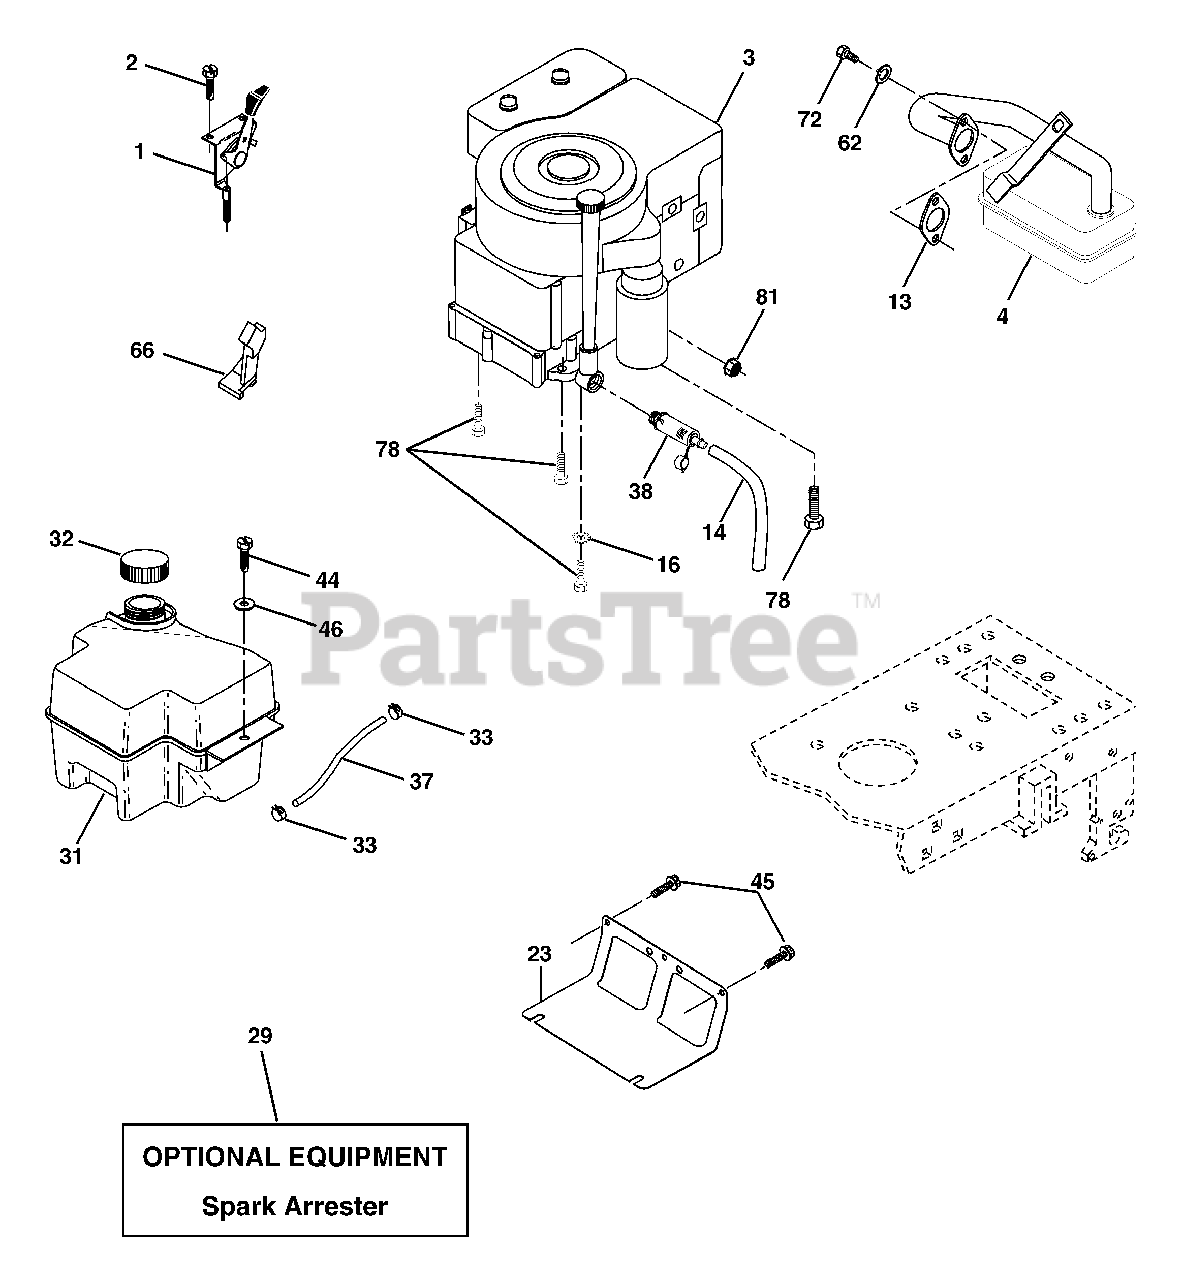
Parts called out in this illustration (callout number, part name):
1	Control Th/ch Flag
2	Screw Hex Thd Cut 1/4-20x5/8 T
4	Muffler LT B&S 12/12.5/13HP
13	Gasket Eng 1 313 Id Tin Plated
14	Tube Drain Oil Easy
16	Washer Lock Ext Tooth 3/8
23	Shield Browning/Debris Guard
29	Kit Spark Arrestor (Flat Scrn)
31	Tank Fuel Front 2 00
32	Cap Asm Fuel W/sym Vented
33	Clamp Hose Black
37	Line Fuel 20"
38	Plug Drain Oil Easy
44	Screw Hexwsh Thdrol 1/4-20x3/4
45	Screw Hex Wsh Thdr 3/8-16 x 3/4
46	Washer 9/32 X 7/8 X 16 Ga
62	Washer Lock Hvy Hlcl Spr 5/16
66	Stop Throttle 3000 RPM
72	Screw Hexhd Cap 5/16-18x 3/4
78	Screw 3/8-16x1-1/4 Smgml Tap/R
81	Nut Keps Hex 1/4-20 Starter Nut
